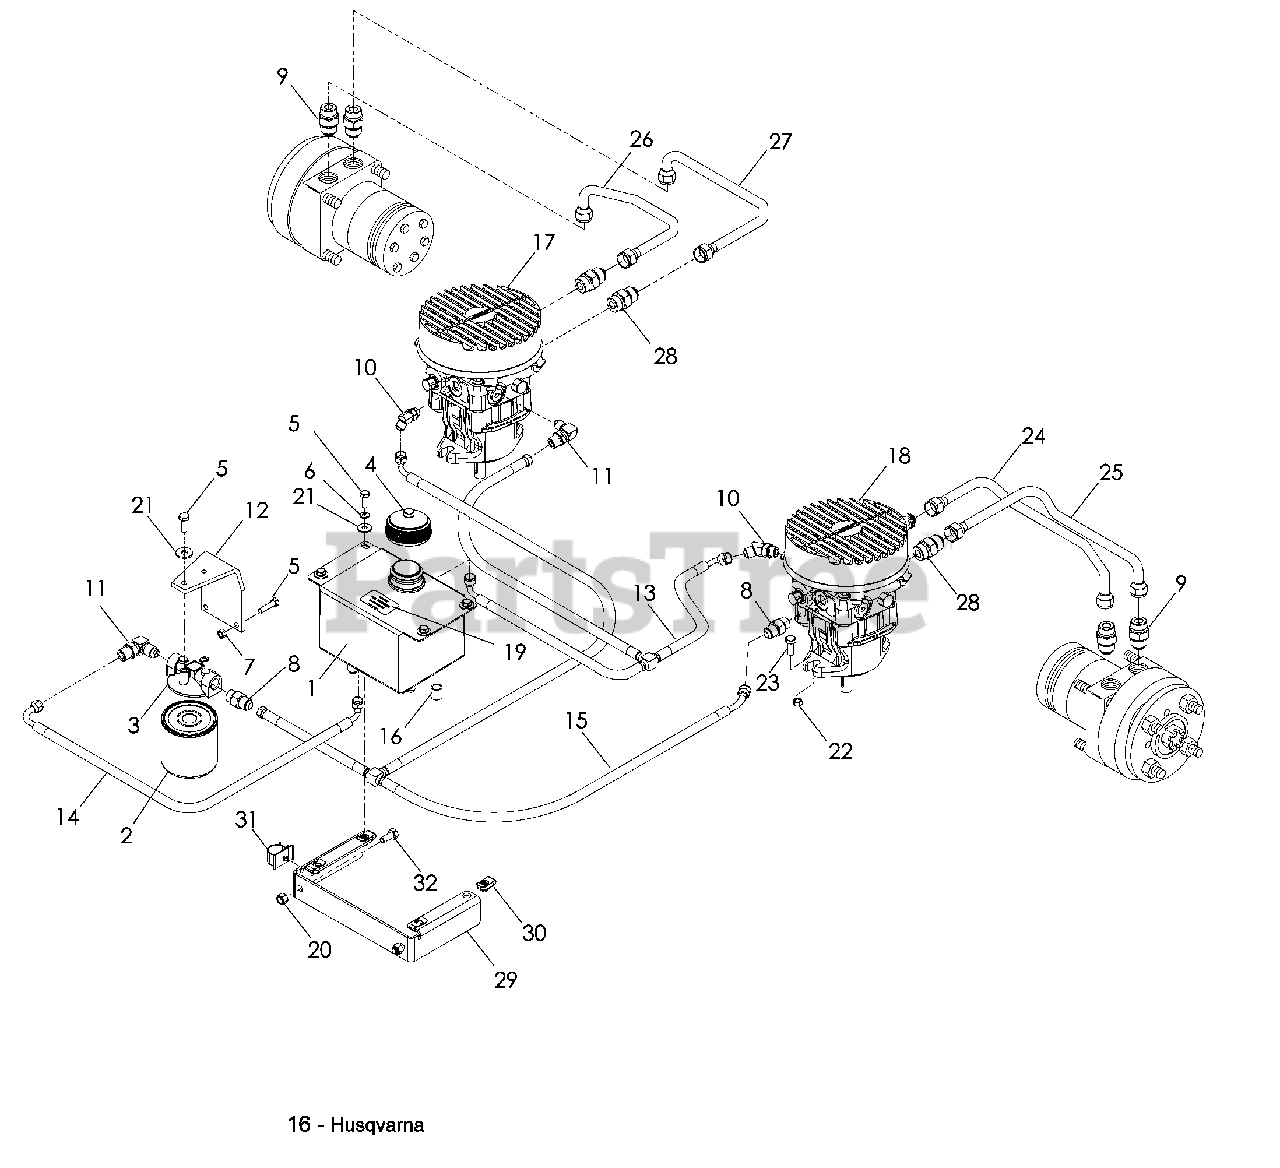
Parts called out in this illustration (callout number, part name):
3	FILTER HEAD
4	HYDRAULIC CAP
5	HCS ¼-20 x ¾
6	LOCKWASHER ¼
7	NUT ¼-20 HEX NYLOC
9	STRAIGHT FITTING
12	BRACKET, FILTER
13	T ASSEMBLY, RETURN
14	HOSE
15	T ASSEMBLY, SUPPLY
17	PUMP w/FAN, 10CC, RT
18	PUMP w/FAN, 10CC, LT
19	DECAL, OIL TANK
20	NUT 5/16-18 HEX NYLOC
21	WASHER ¼ FLAT
22	NUT 3/8-16 CNTRLK
23	HCS 3/8-16 x 1 WHIZLK
24	HYDRAULIC LINE
25	HYDRAULIC LINE
26	HYDRAULIC LINE
27	HYDRAULIC LINE
29	MOUNT, TANK
30	RETAINER, U TYPE
31	CLIP, PUSH MOUNT WIRE
32	HCS 5/16-18 x ¾
